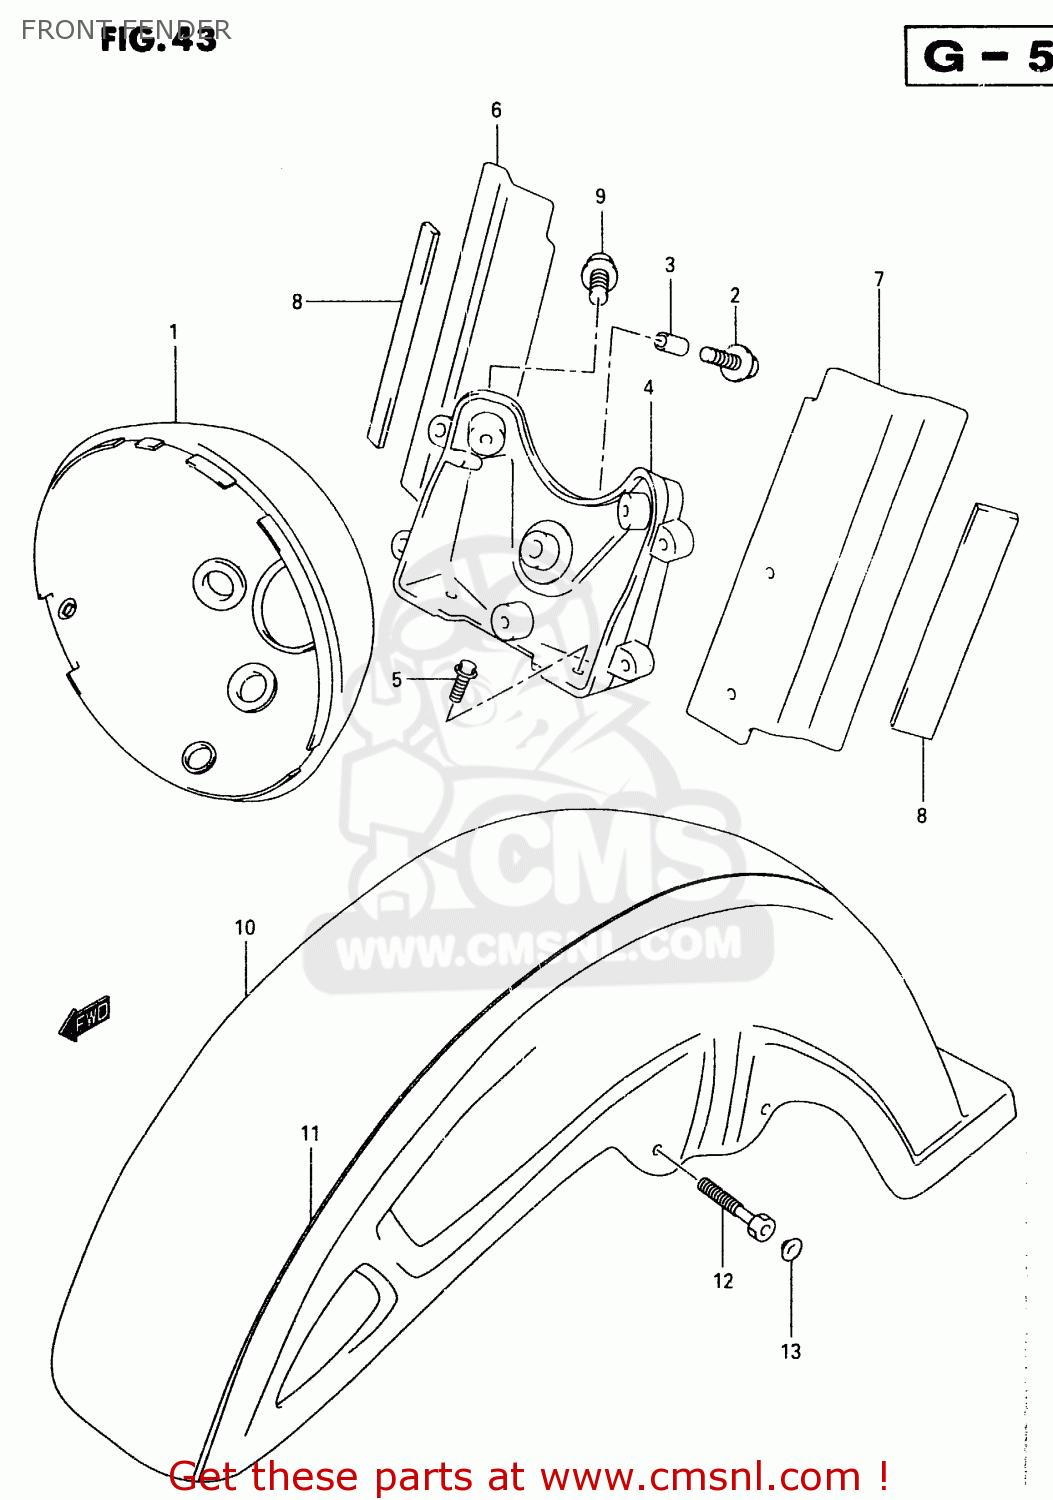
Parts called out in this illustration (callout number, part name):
1	HOUSING,HEADLAMP
2	BOLT(6X25)
3	SPACER(6.8X12X11)
4	BRACKET,HEADLAMP HOUSING
5	BOLT
6	PLATE,HEADLAMP BRACKET,R
7	PLATE,HEADLAMP BRACKET,L
8	PROTECTOR(170X95X3.0)
9	SCREW(6X12)
10	FENDER,FRONT
11	TAPE SET,FR FENDER
12	BOLT
13	CAP(OD:11)
